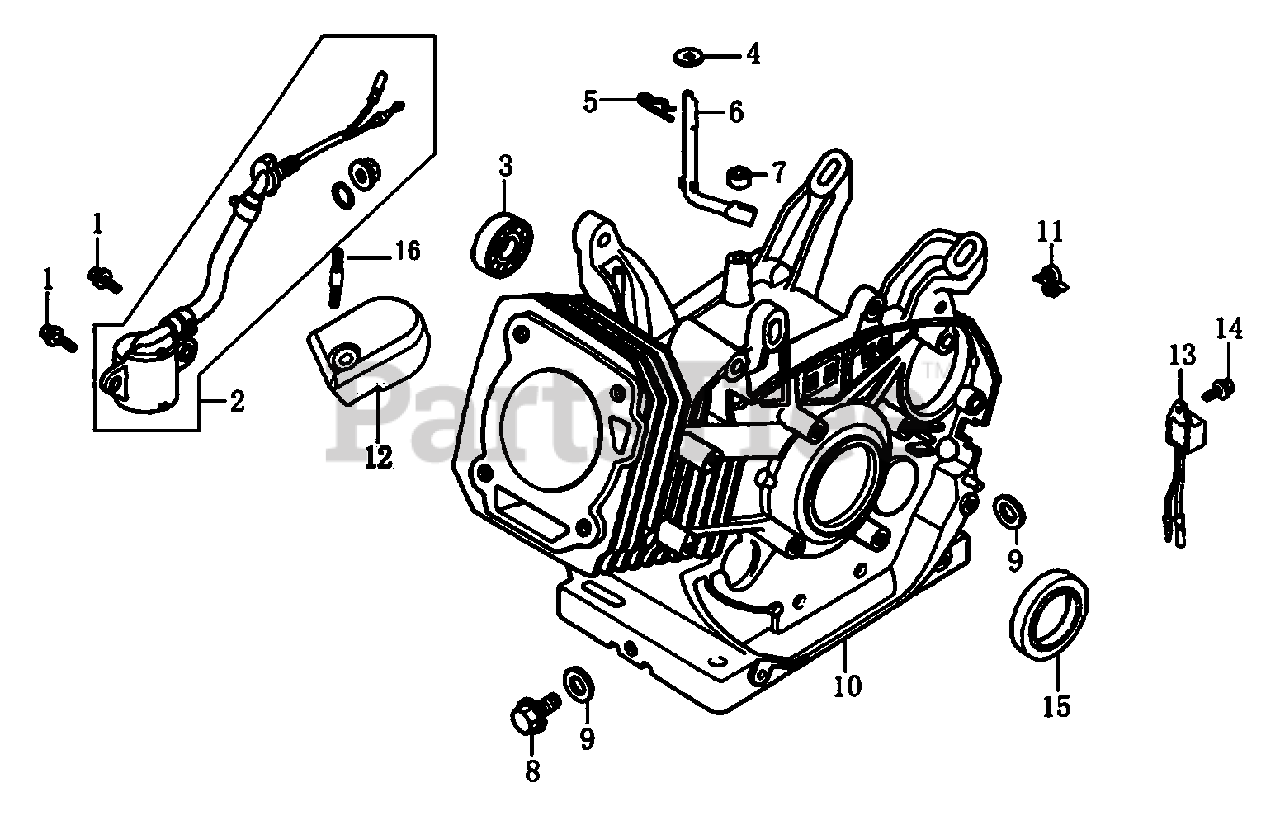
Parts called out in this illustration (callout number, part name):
1	BOLT, FLANGE
2	SWITCH ASSY., OIL LEVEL
3	BEARING, RADIAL BALL 6202
4	WASHER, PLAIN
5	PIN, LOCK 10MM
6	SHAFT, GOVERNOR ARM
7	OIL SEAL, 8X14X4
8	BOLT, DRAIN PLUG
9	WASHER, DRAIN PLUG 12MM
10	CRANKCASE
11	HOLDER, STOP SWITCH
12	COVER, WIRE
13	ALERT UNIT,OIL
14	BOLT, FLANGE 6X12
15	OIL SEAL 35X52X7
16	BOLT, STUD EXHAUST
